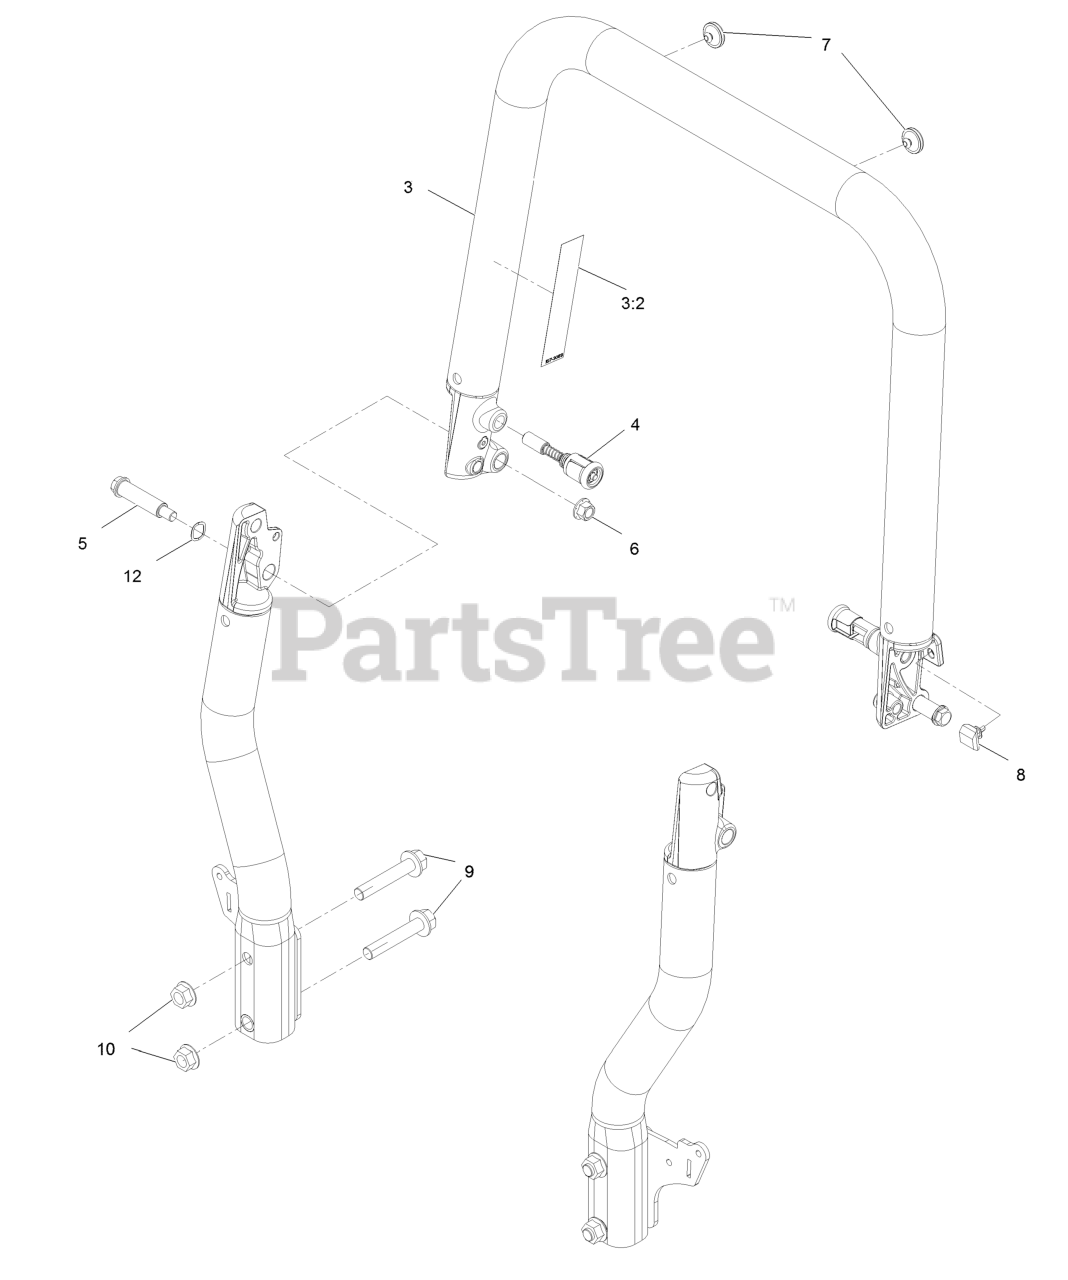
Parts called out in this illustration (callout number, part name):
3	Top Tube ASM
3:2	Decal-Warning
4	Pin-Spring
5	Bolt-Shoulder
6	Nut-Lock
7	Bumper, ROPS
8	Bumper-ROPS
9	Screw-HHF
10	Nut-Flange
12	Washer-Wave
